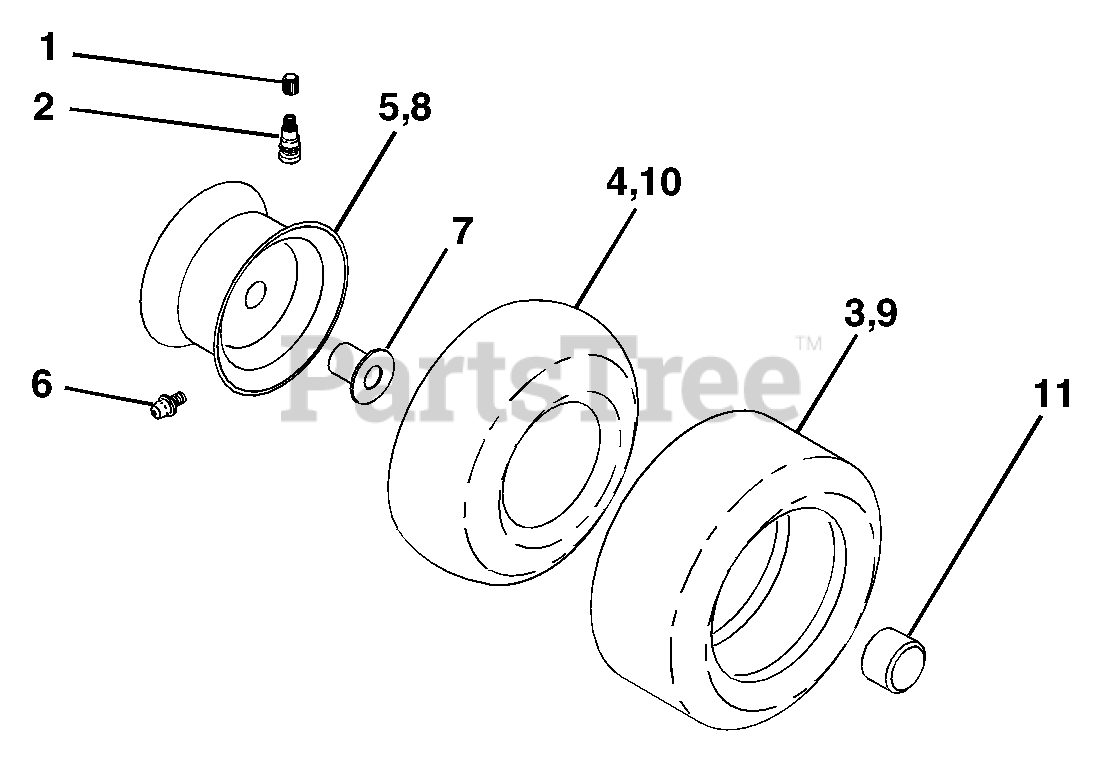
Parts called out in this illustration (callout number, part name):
1	Cap Valve Tire
2	Stem Valve
3	Tire F Ts 15 X 6 0 - 6 Service
4	Tube Front (Service Item Only)
5	Rim Asm 6"front Service
6	Fitting Grease (Front Wheel Only)
7	Bearing Flange (Front Wheel Only)
8	Rim Asm 8"rear Service
9	Tire R Ts 20X10.00-8 C Service
10	Tube Rear (Service Item Only)
11	Cap Axle Blk 1 50 X 1 00
